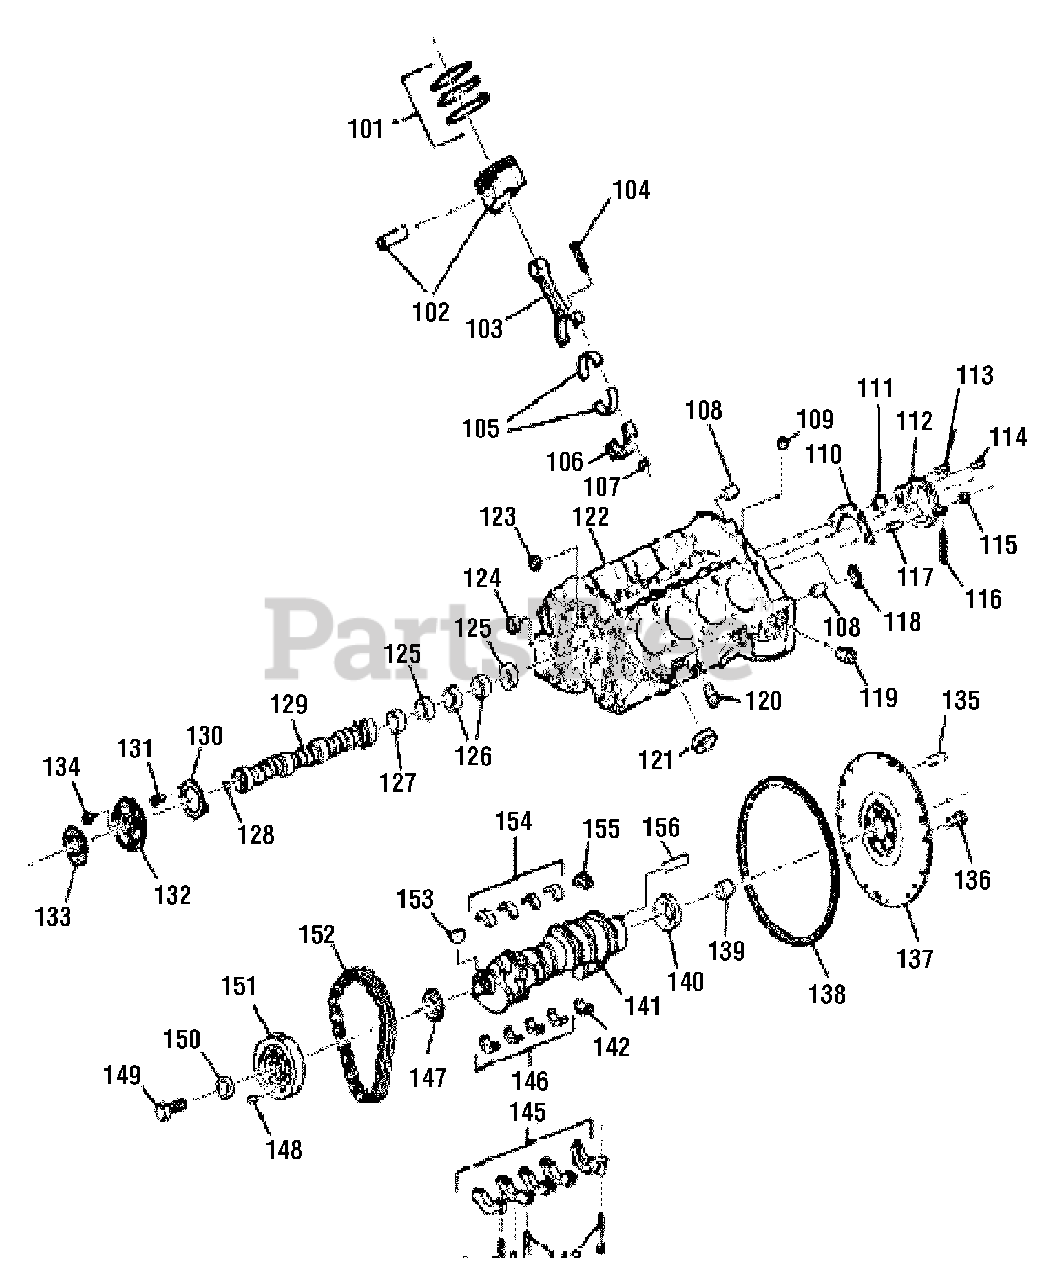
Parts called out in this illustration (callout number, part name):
101	NUT, Hex Nyloc
102	* PISTON
103	* ROD
104	* BOLT
105	* BEARING
106	* CAP
107	* NUT
108	* PIN
109	* PLUG
110	* GASKET
111	* PIN
112	* SEAL
113	* BOLT
114	* BOLT
115	* NUT
116	* STUD
117	* STUD
118	* EXPANSION PLUG
119	* PLUG
120	* PLUG
122	* CYLINDER BLOCK
123	HUB, EZT Transmission
124	NUT, EZT Transmission
128	* PIN
129	* CAMSHAFT
130	* RETAINER
131	* BOLT
132	* SPROCKET
133	* RING
134	* BOLT
135	* WEIGHT
136	* BOLT
137	* FLYWHEEL
138	* GEAR
139	* BEARING
141	* CRANKSHAFT
142	* BEARING
143	* BOLT
144	* STUD
145	* CAP
146	* BEARING
147	* SPROCKET
148	* PIN
149	* BOLT
150	* WASHER
151	* BALANCER
152	* CHAIN
153	* KEY
154	* BEARING
155	* BEARING
156	* PIN
